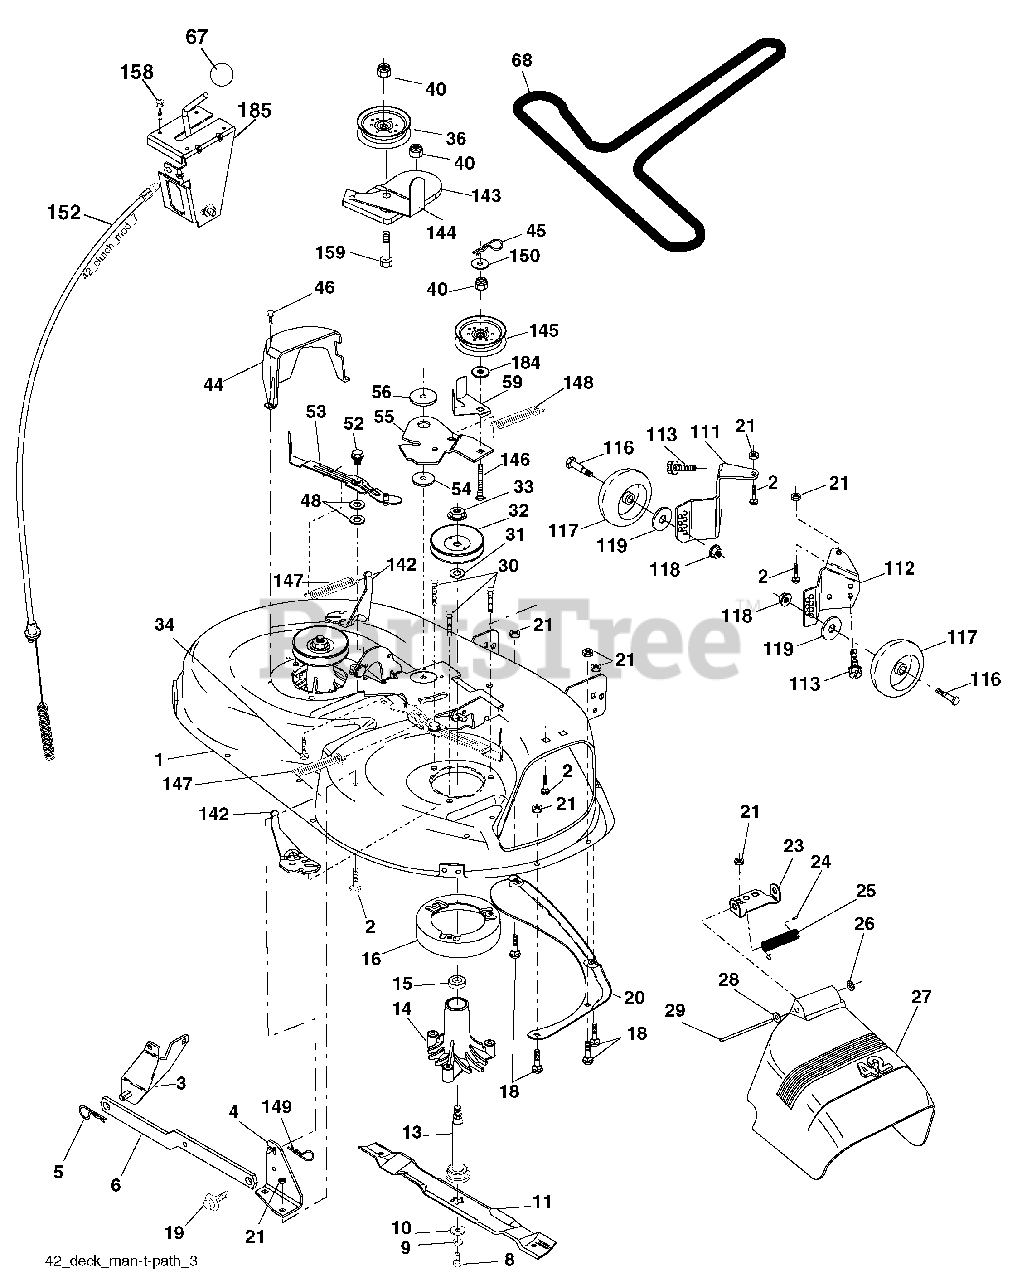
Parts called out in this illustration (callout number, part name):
1	Mower Deck Assembly, 42"
2	Bolt
3	Bracket Asm Fr. Sway Bar 3/42
4	Bracket Asm Deck 42" Sway Bar
5	Retainer Spring
6	Bar Sway Deck
8	Bolt 3/8-24 x 1.25 Gr. 8 patched
9	Washer, Lock
10	Washer, Hardened (The following Blades are available)
11	Blade Mower 42" Hi-Lift (for bagging and discharging)
11	Blade, Mulching 42" Std (for mulching mowers only)
11	Blade Mulching 42" Premium (For better wear when mulching)
13	Shaft As sem bly, Mandrel, Vented
14	Housing, Mandrel, Vented
15	Bearing, Ball, Mandrel
16	Stripper, Mandrel Deck
18	Bolt, Carriage 5/16-18 x 5/8
19	Bolt, Shoulder
20	Baffle, Vortex
21	Nut
23	Bracket, Deflector Mower 42"
24	Cap, Sleeve 80 x 112 Blk Mower
25	Spring, Torsion, Deflector 2 52
26	Nut, Push Phos & Oil
27	Shield, Deflector 42" Blk
28	Washer 11/32 x 5/8 x 16 Ga.
29	Rod, Hinge 42" 6 75 W/G
30	Screw Thdrol
31	Washer, Spacer Mower Vented
32	Pulley, Mandrel
33	Nut, Toplock
34	Bolt Carr SH 3/8-16 x 1-1/2 Gr.5
36	Pulley, Idler, Flat
40	Nut Lock 3/8-16
44	Guard, Mandrel, LH
45	Retainer
46	Screw, Thdrol 1/4-20 x 5/8 T
48	Washer, Hardened
52	Bolt, Shoulder 5/16-18 unc
53	Arm Assembly, Pad, Brake
54	Washer, Hardened
55	Arm, Idler
56	Spacer, Retainer
59	Guard TUV Idler
67	Knob Round
68	V-Belt, 42" Mower
111	Bracket Asm. Whl Ga. LH
112	Bracket Asm Whl Ga. RH
113	Screw 5/16-18
116	Bolt, Shoulder
117	Wheel, Gauge
118	Nut Centerlock 3/8-16
119	Washer 3/8 x 7/8 x 14 Ga.
142	Arm Spring Brake Mower
143	Bracket Arm Idler 42"
144	Keeper Belt 42" Clutch Cable
145	Pulley Idler Flat
146	Bolt Carriage Idler
147	Spring Extension
148	Spring Return Idler
149	Retainer Spring Yellow
150	Washer 9/32 x 3/4 x 10 Ga.
152	Clutch Cable 42"
158	Screw Hex Thd Cut 1/4-20 x 1/2
159	Bolt Rdhd Sqn 3/8-16 unc x 1-3/4
184	Washer 13/32 x 7/8 x 10 Ga.
185	Head Asm Cable Clutch
185	Mandrel Assembly
185	Replacement Mower, Complete (Std. deck-Order seperately gauge wheel componants Key Nos. 116-119)
